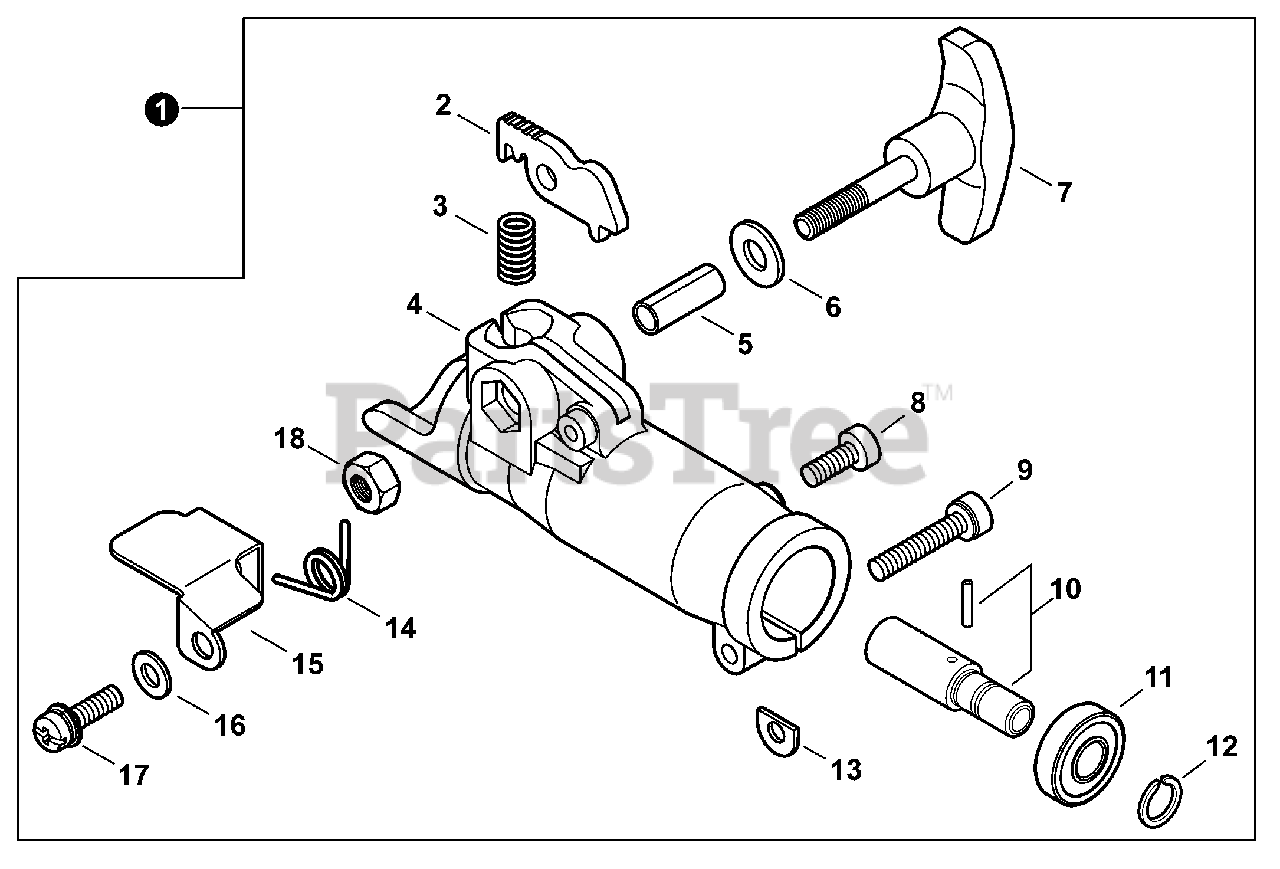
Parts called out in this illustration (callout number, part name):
1	COUPLER ASSY
3	SPRING, COIL
4	HOUSING, COUPLER
5	SLEEVE, KNOB 6xL= 22
6	WASHER 6
7	KNOB, COUPLER SCREW
8	BOLT 5x12
9	BOLT M5x25
10	SHAFT, COUPLER
11	BEARING, BALL 609ZZ
12	RING, SNAP ?9
13	D-WASHER
14	SPRING, TORSION
15	PROTECTOR, LATCH
16	WASHER 5
17	SCREW M5x12
